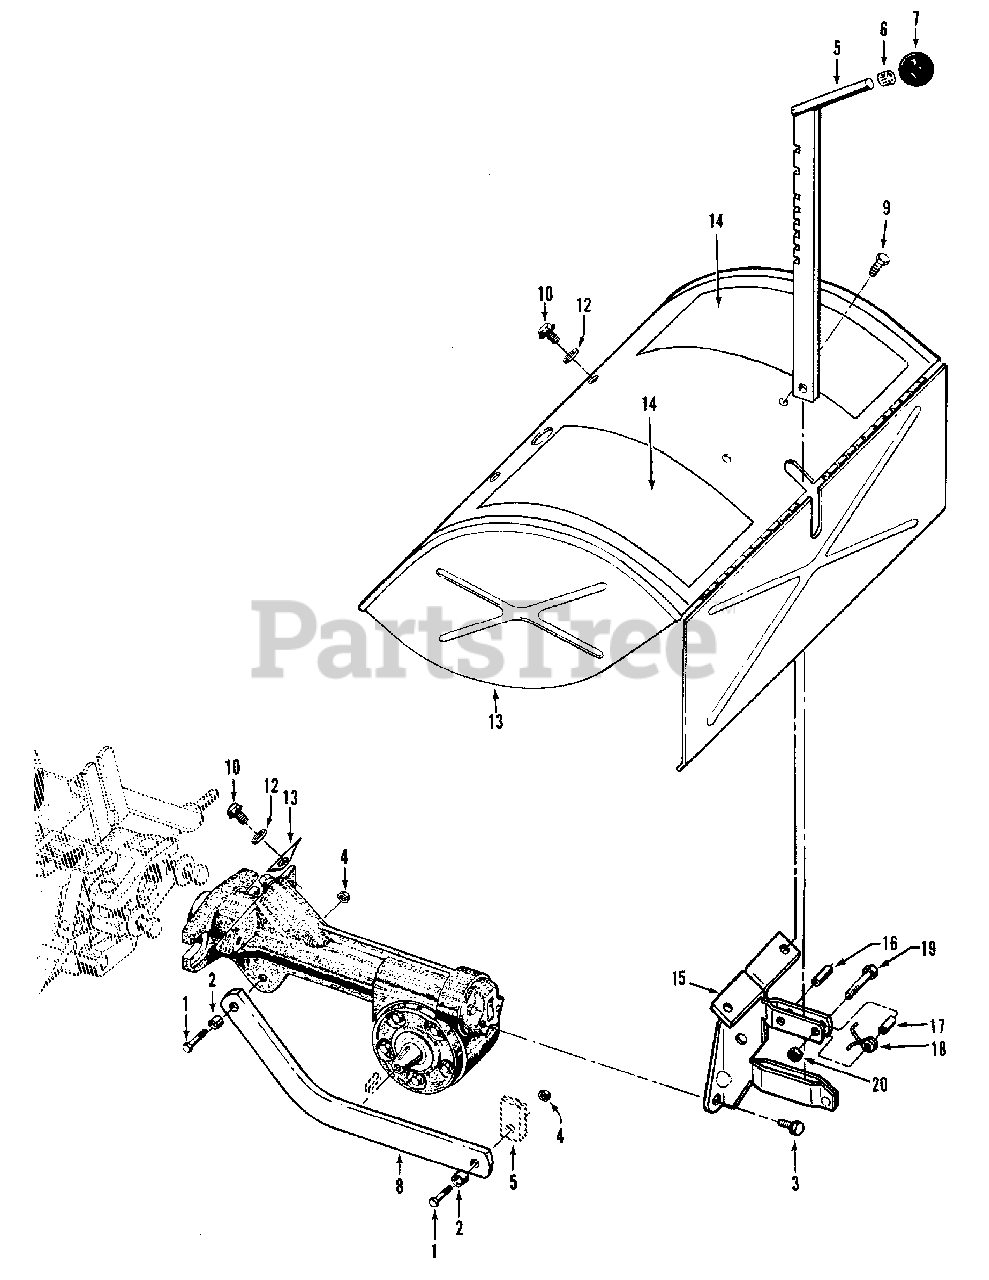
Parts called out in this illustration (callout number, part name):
1	Bolt-hex hd., 3/8-16 x 1-1/4"
2	Bushing-19/64" (.300" lg.)
3	Bolt-flanged hex, 5/16-18 x 5/8"
4	Nut-hex, 3/8"-16
5	Bar-depth regulator
6	Ring-retaining
7	Knob-depth regulator
8	Bar-drag, depth regulator
9	Screw-thread-forming, 1/4-20 x 1/2"
10	Bolt-flanged hex hd, 5/16-18 x 3/4"
12	Washer-flat, 5/16"
14	Decal-hood, operating instructions (LH)
14	Decal-hood, operating instructions (RH)
16	Pin-roll (Spirol) 1/4" x 1"
17	Spacer, Split
19	Bolt-hex hd., 1/4-20x1
20	Locknut-1/4"-20
